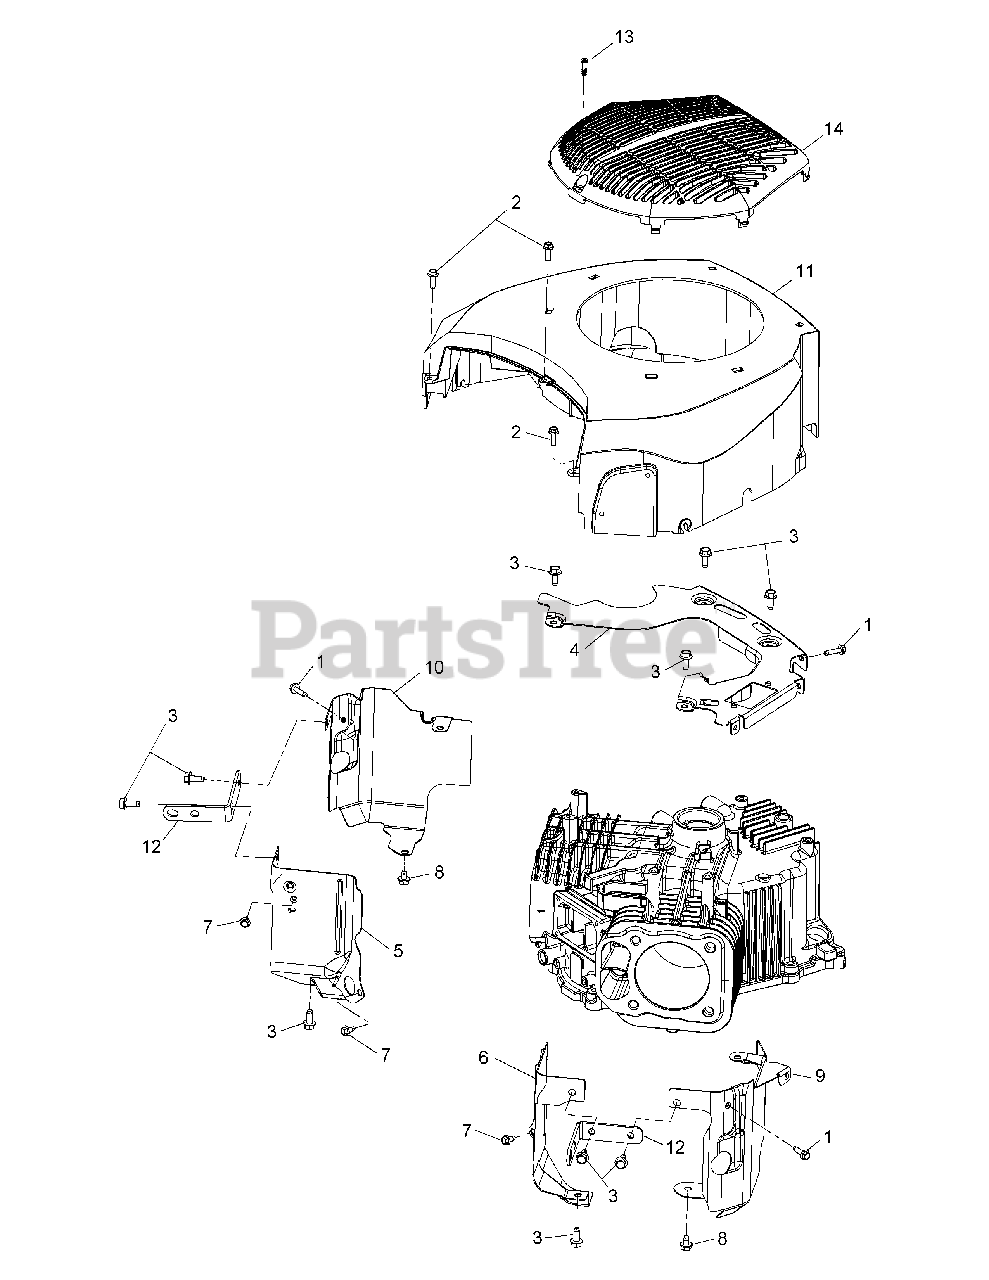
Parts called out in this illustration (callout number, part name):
1	Thread Forming Screw
3	Thread Forming Screw
4	Backing Plate
5	Valley Baffle, #1 Cylinder
6	Valley Baffle, #2 Cylinder
7	Thread Forming Screw
8	Thread Forming Screw
9	Left Barrel Baffle
10	Right Barrel Baffle
11	Blower Housing
13	Screw, M5-2.42
